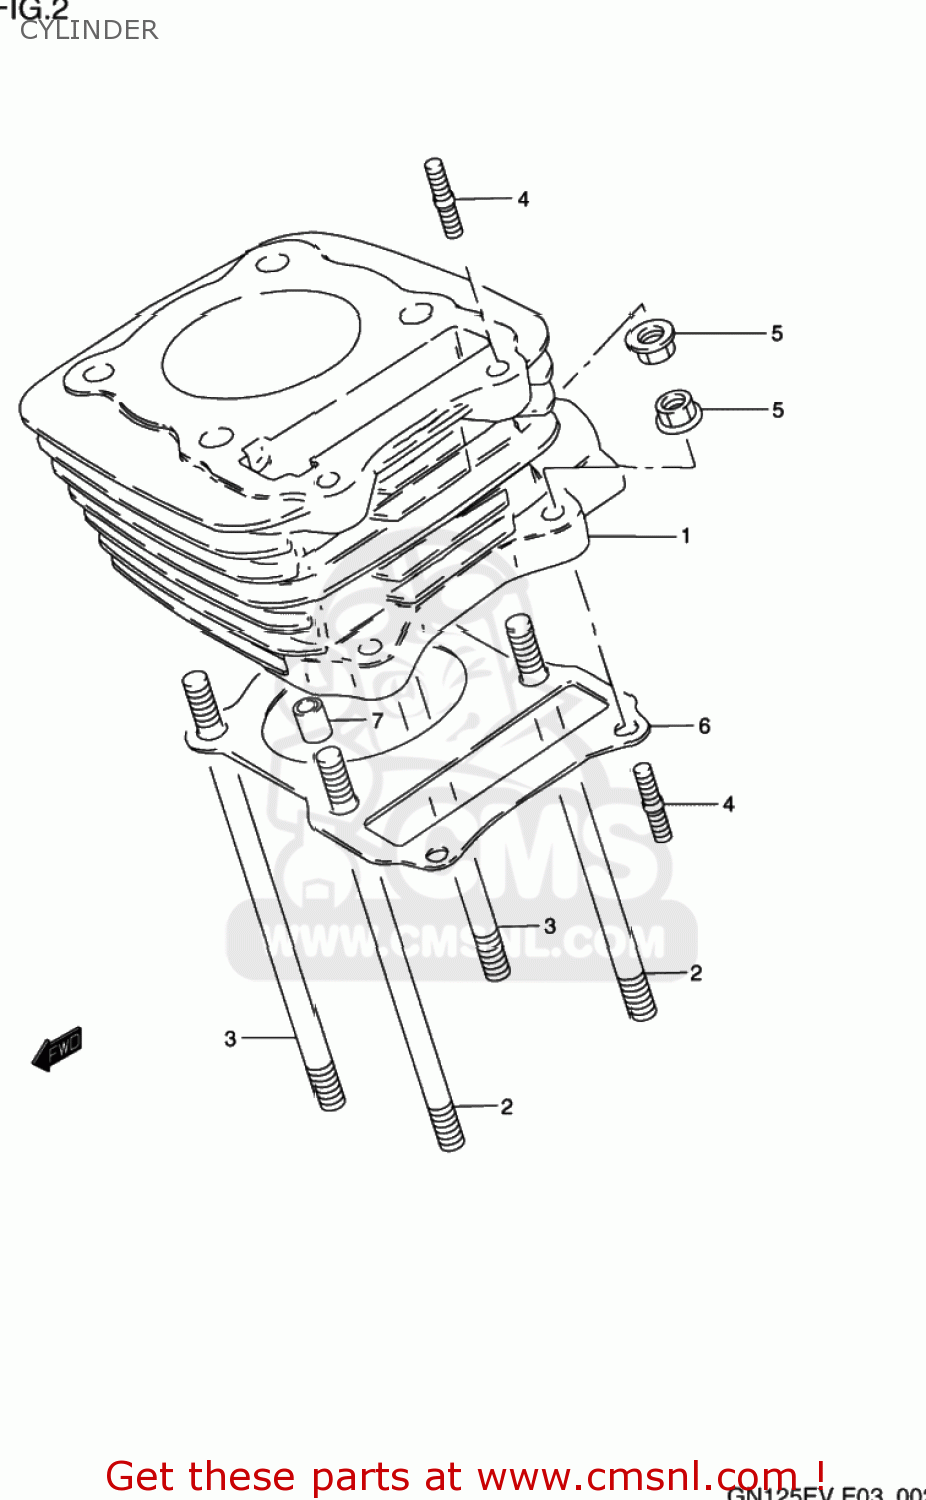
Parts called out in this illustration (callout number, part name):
1	CYLINDER
2	BOLT,STUD
3	BOLT,STUD
4	BOLT,STUD
5	NUT
6	GASKET,CYLINDER (NAS)
7	PIN
